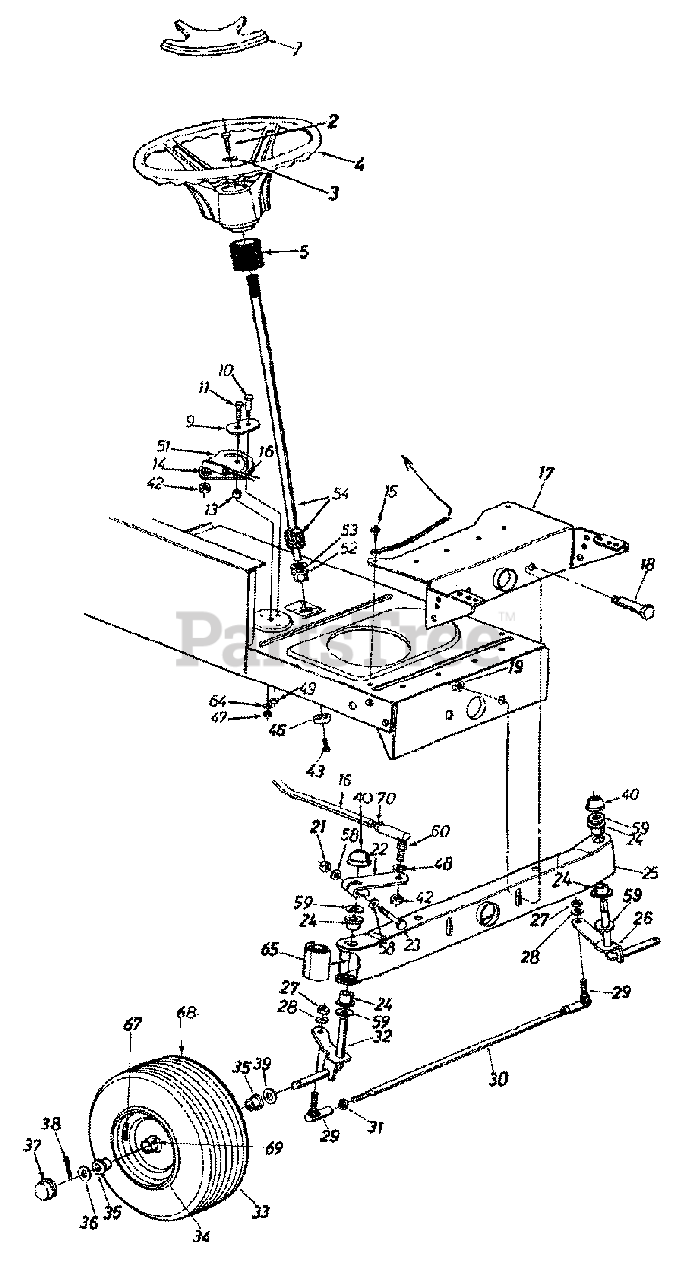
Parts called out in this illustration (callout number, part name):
1	Steering Wheel Cap
2	Hex Bolt 5/16-18 x 1" Lg.
3	Belleville Wash. .345" I.D.
4	Steering Wheel
5	Steering Bellow-9"
9	Retainer Plate
10	Shoulder Bolt .437" Dia. x .35 Lg. 5/16-18 Thd.
11	Hex Bolt 3/8-24 x 1.0" Lg. (Gr. 5)
13	Spacer .380" I.D. x .625" O.D. x .227
14	L-Wash. 3/8" I.D. (H.D.)
15	Hex Wash. Hd. Self-Tap Scr.
16	Steering Drag Link
18	Shoulder Bolt .498" Dia. x 2.04 Lg. 3/8-16 Thd.
19	Flanged L- Nut 3/8-16 Thd.
21	Hex L-Nut 5/16-24 Thd.
22	Steering Arm Front Axle
23	Hex Bolt 5/16-24 x 2.00" Lg. (Gr.5)
24	Hex Flg. Brg. .632 I.D.
26	Front Axle Ass'y.-L.H.
27	Hex Nut 3/8-24 Thd.
28	L-Wash. 3/8" I.D.
29	Ball Joint 3/8-24 Thd.
30	Tie Rod (Adjustable)
31	Hex Jam Nut 3/8-24 Thd.
32	Front Axle Ass'y.-R.H.
36	Fl-Wash. .635 I.D. x 1.59" O.D.
37	Front Wheel Hub Cap
38	Cotter Pin 1/8" Dia. x 1.25"
39	Fl-Wash.5/8" x 1.004 x .120
40	Push Cap 5/8" Dia. Rod
42	Hex Jam Nut 3/8-24 Thd.
43	Hex Patch Bolt 5/16-18 x .62"
46	Cap
47	Hex Cent. L-Nut 3/8-24 Thd.
48	L-Wash. 3/8" I.D.
49	Hex Cent. L-Nut 5/16-18 Thd.
51	Steering Gear Segment
52	Hex Flg. Brg. .634 I.D.
53	Fl-Wash. (Hardened)
54	Steering Shaft
58	Wave-Wash. .32" I.D. x .62" O.D.
59	Fl-Wash. (Hardened)
60	Drag Link Ball Joint 7/16-20 Thd.
64	Bell-Wash. .39" I.D. x 1.38" O.D.
65	Pivot Bar End Cap
67	Valve - Air
69	Grease Fitting
70	Jam Nut 7/16-20
